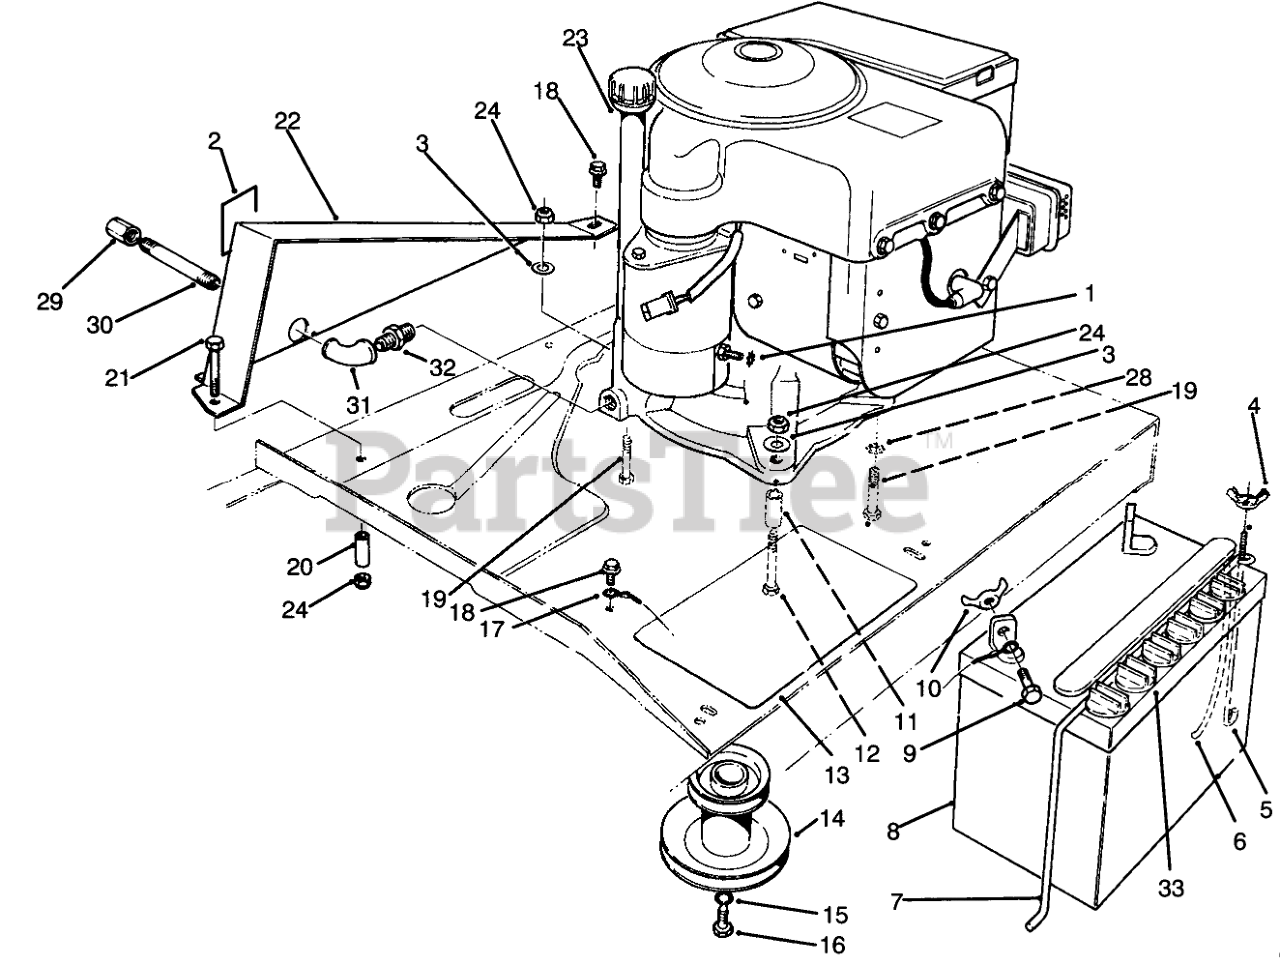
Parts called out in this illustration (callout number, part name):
1	WASHER-LOCK/EXT
2	DECAL-EUROPE
3	WASHER-PLAIN
4	NUT-WING SPECL
5	POST-BATTERY
6	TUBE-BATT DRAIN/80-2600
7	HOLDDOWN-BATTERY
8	Battery
9	SCREW-HH
10	NUT-WING
11	SPACER-PIVOT
12	SCREW-HH
13	PAD-SKID, ANTI
14	Pulley-Engine
15	WASHER-FLAT
16	SCREW-HH
17	WIRE ASM(BATT/GRD.
18	SCREW-HWHTF
19	SCREW-HH
20	GUIDE-BELT
21	SCREW-HH
22	GUIDE-CHAIN
23	Engine-8 H.P. B & S
24	NUT-LOCK, NI
28	WASHER-LOCK
29	CAP-PIPE
30	NIPPLE-PIPE
31	ELBOW-STREET
32	BUSHING-PIPE
33	BATTERY CAP
